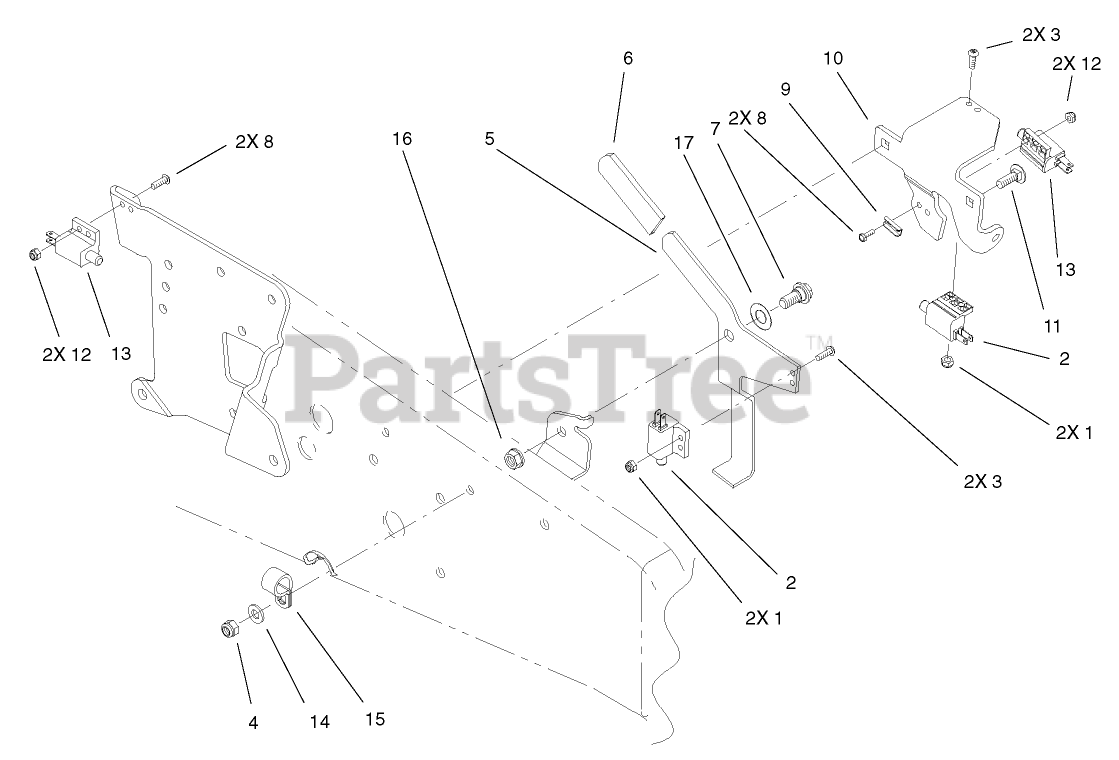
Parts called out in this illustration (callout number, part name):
1	NUT-LOCK, NI
3	SCREW-HSH
4	NUT-LOCK, NI
5	LATCH-BRAKE, PARKING
7	BOLT-SHOULDER
8	SCREW
9	RETAINER-SCREW
10	BRACKET-SWITCH
11	SCREW-CARR
12	NUT-LOCK
13	SWITCH-POLE, SINGLE
14	WASHER-PLAIN
15	CLAMP - R
16	NUT-HEX
17	WASHER
